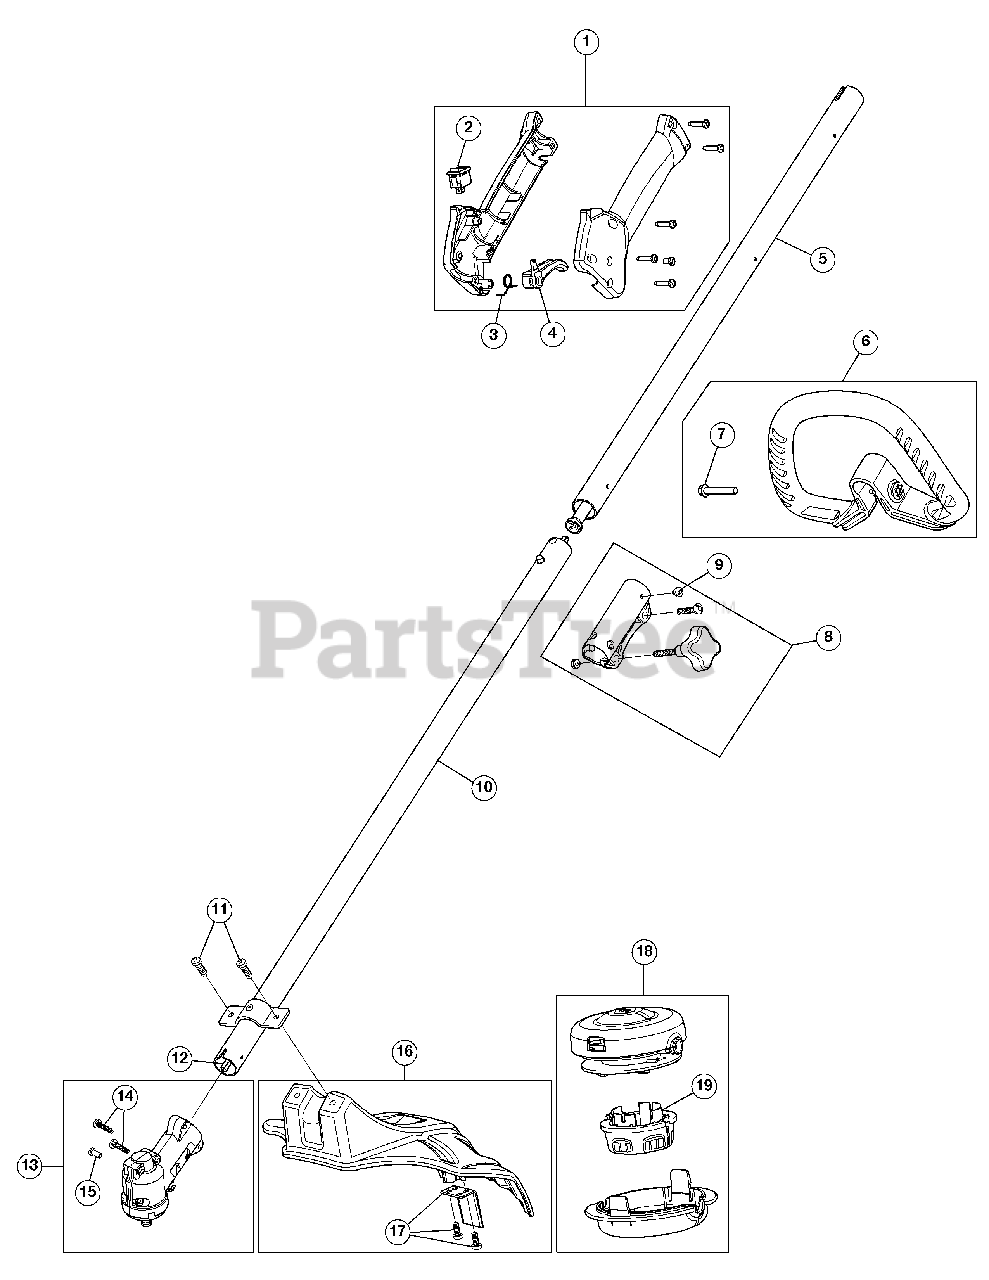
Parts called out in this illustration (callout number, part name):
1	Throttle Housing Assembly (Incl. 2 - 4)
2	Switch Assembly
3	Throttle Trigger Spring
4	Throttle Trigger
5	Upper Drive Shaft Assembly
6	D-Handle Assembly (Incl. 7)
8	Split Boom Coupler (Incl. 9)
9	Coupler Anti-Rotation Screw
10	Lower Drive Shaft Housing
11	Shield Mounting Screws
12	Lower Flexible Drive Shaft
13	Gearbox Assembly (Incl. 14 and 15)
14	Anti-Rotation Screw
15	Gearbox Mounting Hardware
16	Shield Assembly (Incl. 17)
17	Blade Assembly
18	Cutting Head Assembly (Incl. 19)
